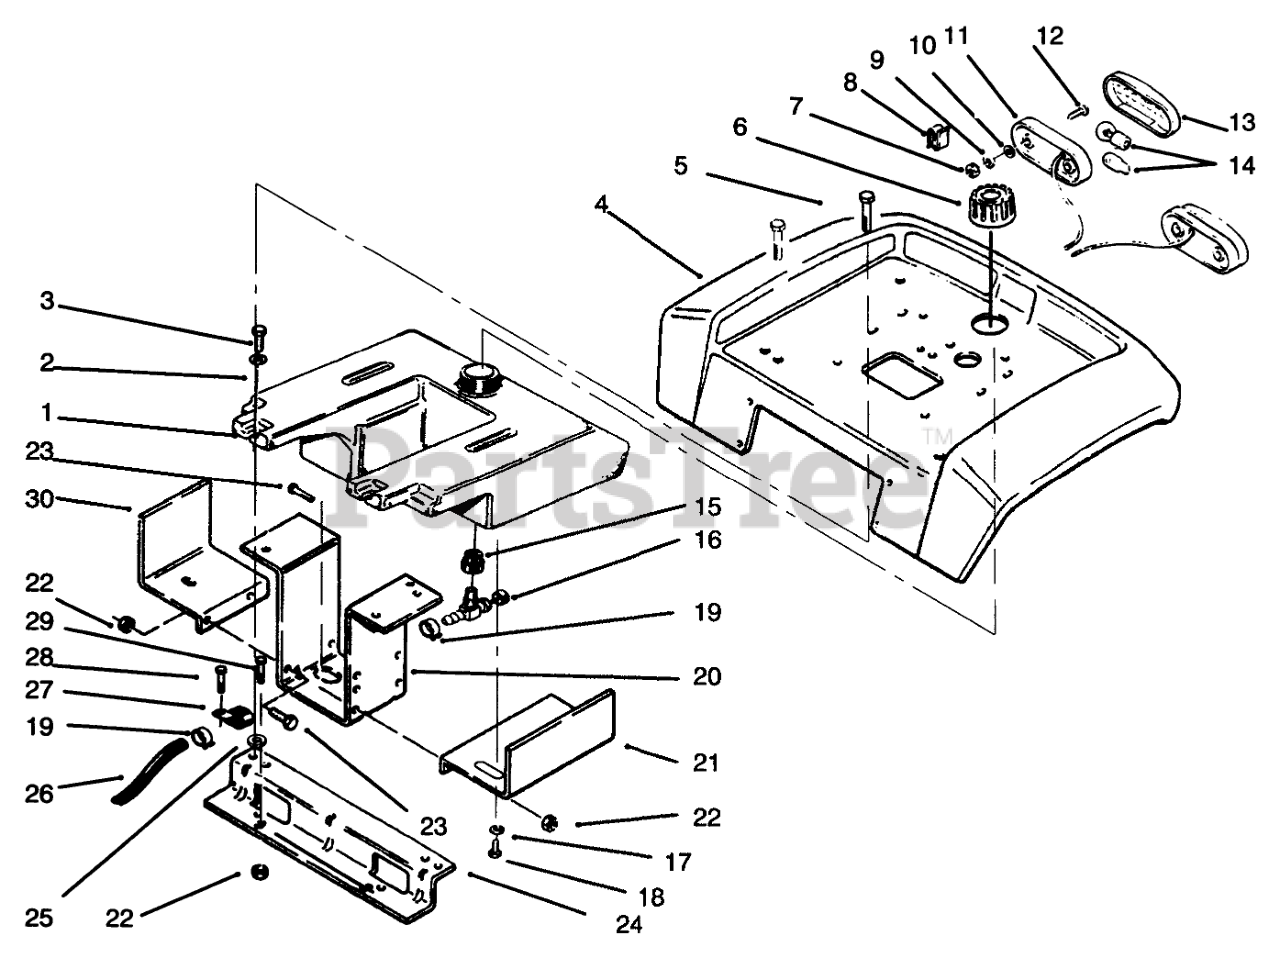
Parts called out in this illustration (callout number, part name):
1	TANK-FUEL
2	WASHER-FLAT
3	Bolt
4	Fender
5	Bolt
6	GAS CAP ASM
7	NUT-LOCK, NI
8	SPEED CLIP
9	WASHER-FLAT
10	WASHER-LOCK, INT
11	BASE-TAIL LIGHT
12	Screw
13	LENS-TAIL LIGHT
14	Bulb
15	BUSHING
16	VALVE-FUEL
17	WASHER-LOCK
18	SCREW-HH
19	CLAMP-HOSE
20	Bracket-Fender
21	Fuel Tank Support LH
22	NUT-LOCK, NI
23	SCREW-HH
24	BRACKET-FENDER B
25	WASHER-PLAIN
26	Line-Fuel 62"
27	CLIP
28	SCREW-HH, LOCK
29	SCREW-HH
30	Support-FueITank RH
